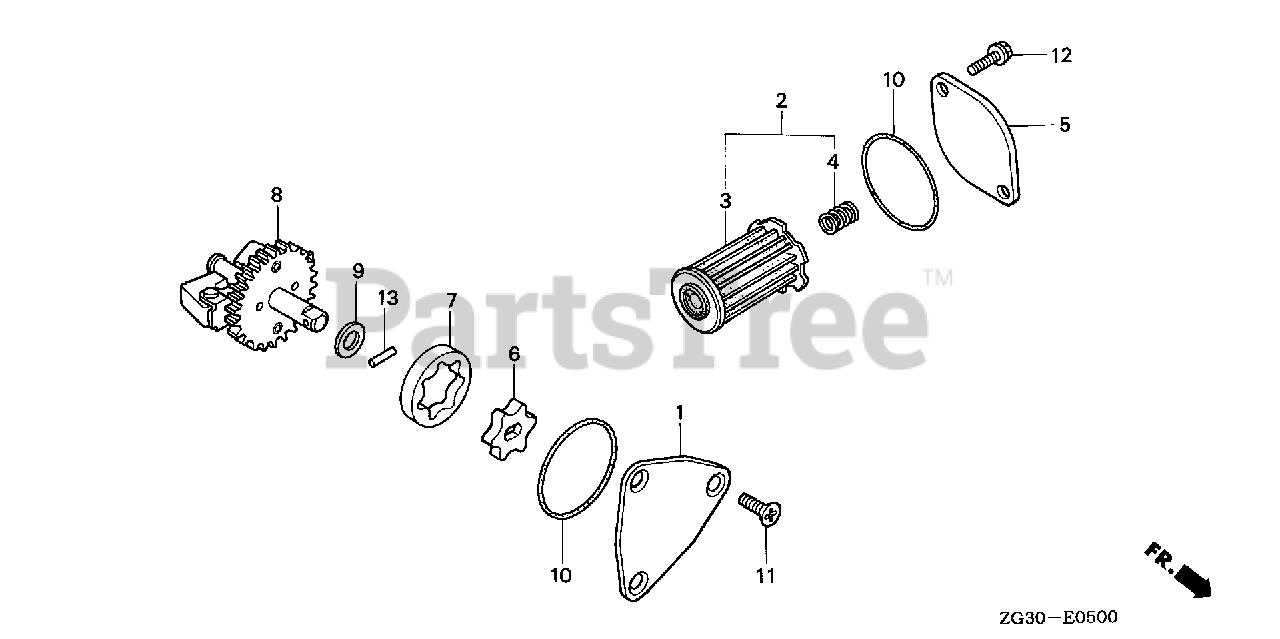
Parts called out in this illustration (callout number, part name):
1	COVER, OIL PUMP
2	STRAINER, OIL
3	STRAINER, OIL (NOT AVAILABLE)
4	SPRING, OIL STRAINER
5	COVER, OIL STRAINER
6	ROTOR, OIL PUMP (INNER)
7	ROTOR, OIL PUMP (OUTER)
8	WEIGHT, GOVERNOR
9	WASHER (15.5MM)
10	O-RING (42.2X2.4)
11	SCREW, FLAT (6X16)
12	BOLT, FLANGE (6X16)
13	ROLLER (3X13.4)
